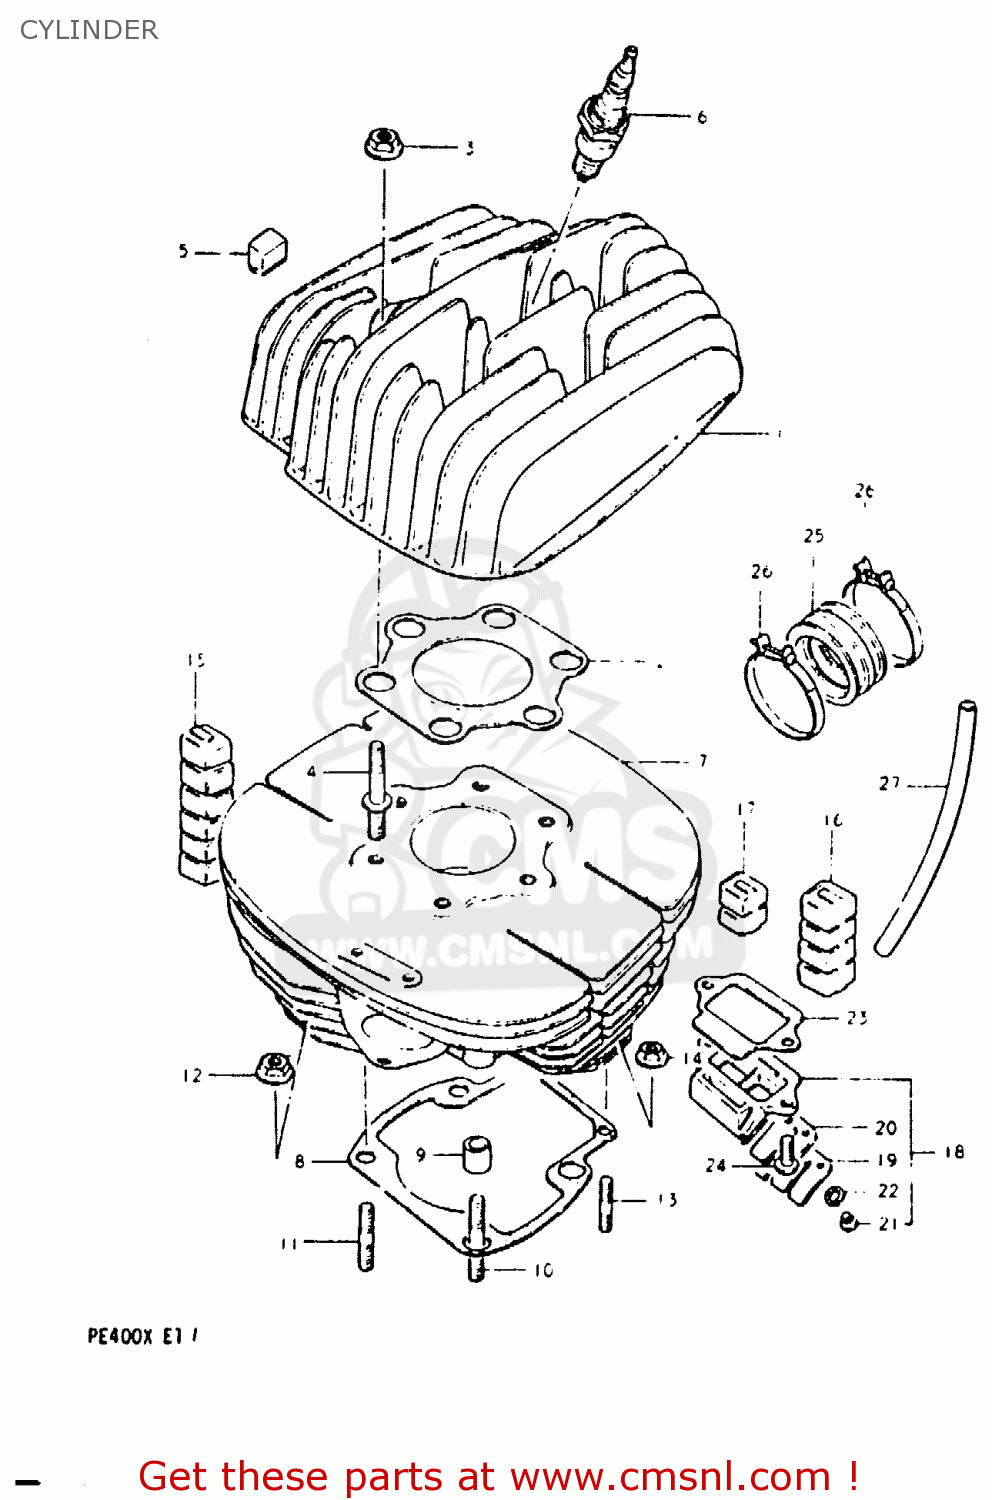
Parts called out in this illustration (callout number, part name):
1	HEAD,CYLINDER
2	GASKET (T:2.0)
3	NUT
4	BOLT,STUD
5	PAD,CYLINDER HEAD
6	SPARK PLUG BR9EV
7	CYLINDER
8	GASKET,CYLINDER (MCA)
9	PIN
10	STUD BOLT (L:40)
11	STUD 10X25
12	NUT
13	STUD 6X20
14	NUT
15	PAD,CYLINDER
16	PAD,CYLINDER
17	PAD,CYLINDER
18	VALVE ASSEMBLY,REED
19	STOPPER,REED VALVE
20	VALVE,REED
21	SCREW
22	LOCK WASHER
23	GASKET,REED VALVE (MCA)
24	SCREW
25	PIPE,INTAKE
26	CLAMP
27	HOSE
